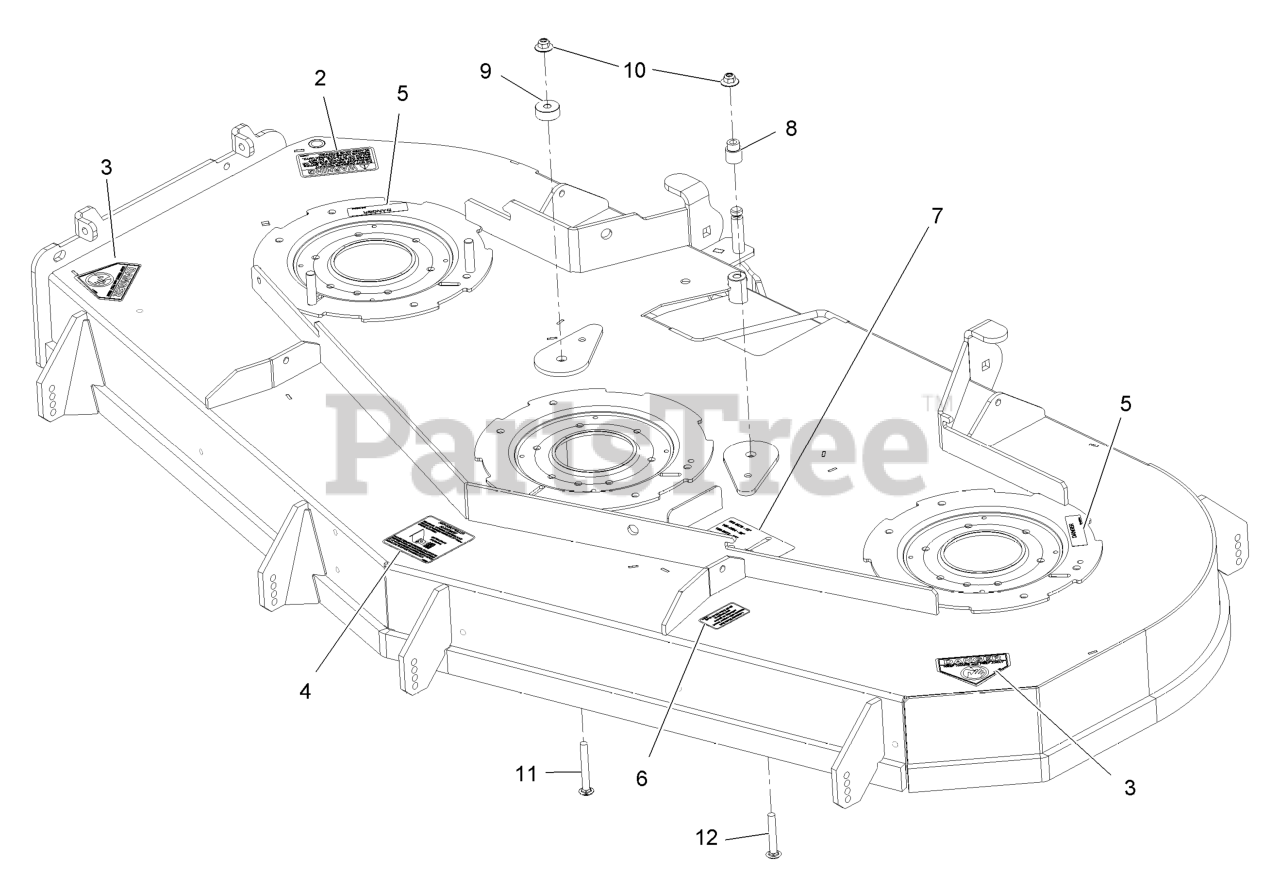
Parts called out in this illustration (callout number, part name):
2	DECAL-WARNING, DISCHARGE
3	DECAL-DANGER
4	DECAL,ANTISCALP
5	DECAL-COVER, MISSING
6	DECAL,BOLT TORQUE
7	DECAL,BELT ROUTING
8	BUSHING-IDLER
9	SPACER-IDLER
10	Nut-Nyloc 3/8-16 Flg
11	SCREW-CARR
12	SCREW-CARR
